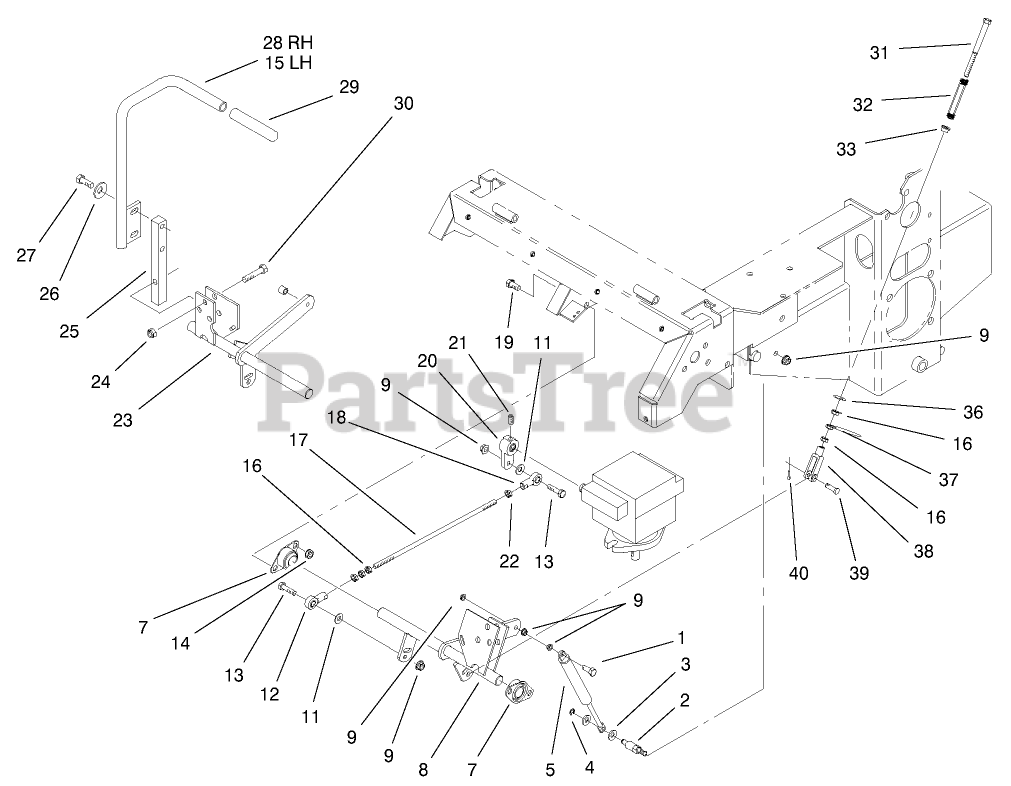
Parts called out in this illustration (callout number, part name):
1	SCREW-HH
2	PIN-DAMPER
3	WASHER-PLAIN
4	RING-RETAINING, EXT
5	DAMPER-CONTROL
7	BEARING-FLANGE, SIDE
8	CONTROL-MOTION, LH
9	NUT-HF
11	WASHER-FLAT
12	BALLJOINT-RH
13	SCREW-HH
14	NUT-HHF, WHIZ
15	LEVER-CONTROL, LH
16	NUT-HEX
17	LINKAGE-PUMP/LEVER
18	BALLJOINT-LH
19	SCREW-HH
20	ARM-CONTROL, PUMP
21	SCREW-SET
23	CONTROL-MOTION, RH
24	NUT-LOCK, NI
25	ARM-CONTROL, SHAFT
26	WASHER-BELLEVILLE
27	SCREW-HH
28	LEVER-CONTROL, RH
29	GRIP-CONTROL, MOTION
30	SCREW-HH
31	BOLT-RETURN, NEUTRAL
32	SPRING-RETURN, NEUTRAL
33	BUSHING-FLANGED
36	WASHER-FLAT
37	NUT-JAM
38	YOKE-ADJUSTABLE
39	PIN-CLEVIS
40	PIN-COTTER
